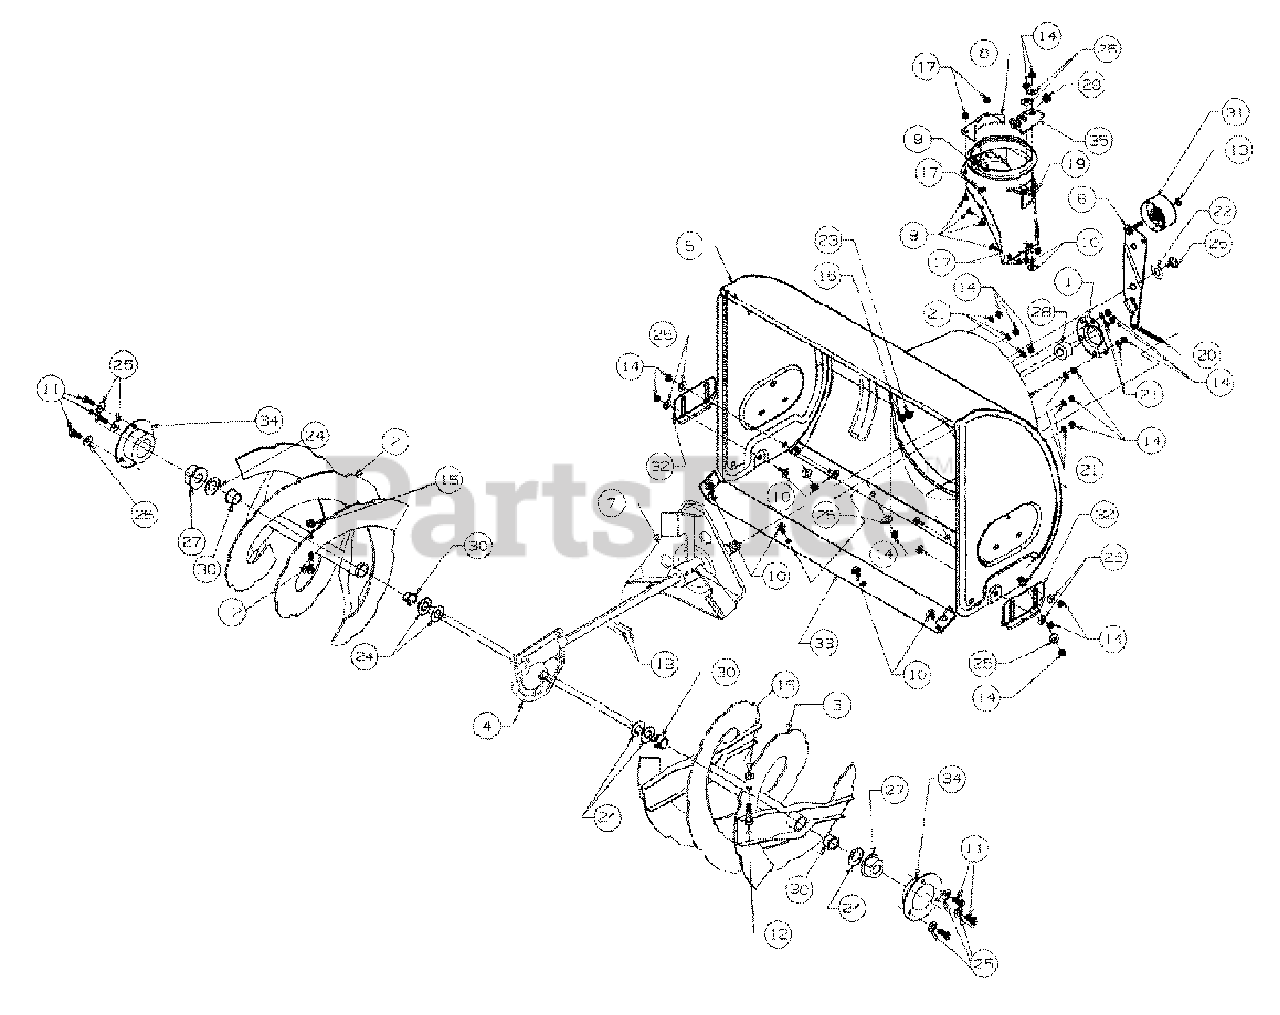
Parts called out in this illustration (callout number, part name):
1	Housing-Bearing
2	Spiral Assembly-L.H. 22"
2	Spiral Assembly-L.H. 24"
2	Spiral Assembly-L.H. 26"
2	Spiral Assembly-L.H. 30"
3	Spiral Assembly-R.H. 22"
3	Spiral Assembly-R.H. 24"
3	Spiral Assembly-R.H. 26"
3	Spiral Assembly-R.H. 30"
4	Gear Assembly 22"
4	Gear Assembly 24"
4	Gear Assembly 26"
4	Gear Assembly 30"
7	Impeller Assembly
9	Screw-Carriage
10	Screw-Carriage
11	Screw-Hex
12	Shear Bolt
13	Nut-Hex Lock
14	Nut-Hex
15	Nut-Hex
16	Nut-Hex
17	Nut-Hex Lock
18	Pin-Spring
19	Adapter-Chute
20	Spring
21	Washer-Lock
22	Washer-Flat
23	Washer-Lock
24	Washer-Flat
25	Washer-Bell
26	Screw-Shoulder
27	Bearing-Flange
28	Bearing-Ball
29	Bushing-Plastic
30	Bushing-Flange
31	Idler-Flat
33	Shave Plate 22"
33	Shave Plate 24"
33	Shave Plate 26"
33	Shave Plate 30"
34	Housing-Bearing
35	Bracket-Chute Crank
